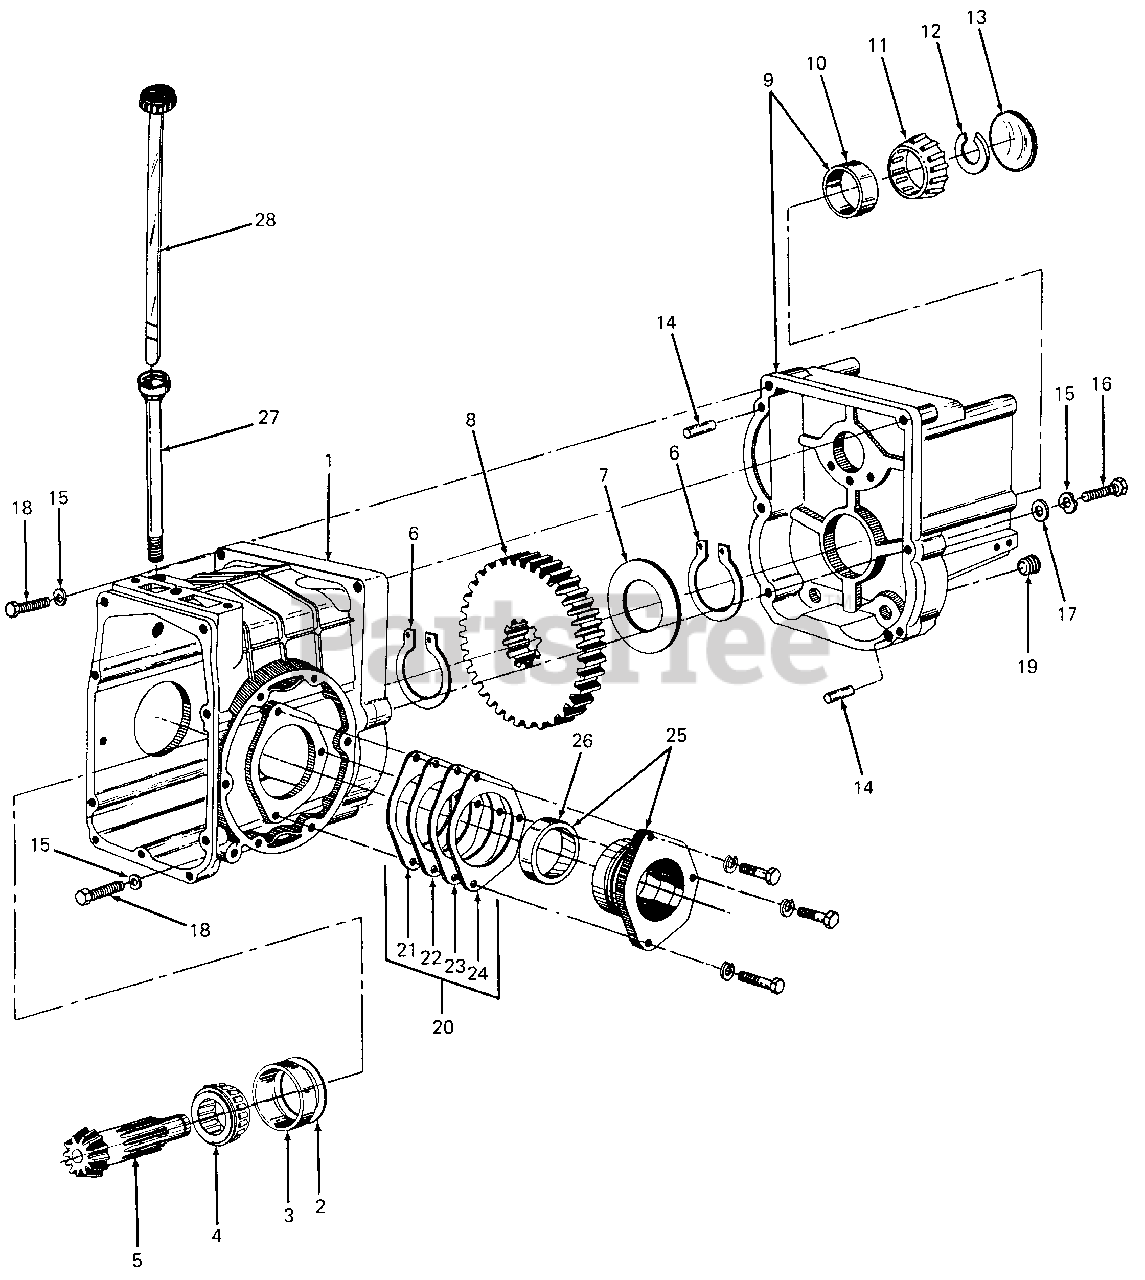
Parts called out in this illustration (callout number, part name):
1	Housing Assy, Rear Transaxle
2	Shim, Rear Bearing Cup, .004 Thk
3	Cup, Roller Bearing
4	Cone, Roller Bearing
5	Shaft, Bevel Pinion
6	Ring, Retaining, 1.312 Dia
7	Spacer, Gear
8	Gear, Reduction - 66T
9	Housing Assy, Adapter w/Cup
10	Cup, Roller Bearing
11	Cone, Roller Bearing
12	Retainer, Front Bearing, .125 Thk
13	Plug, Expansion, 2.12 OD
14	Pin, Dowel, 3/8 Dia X 5/8 Lg
15	Washer, Spring, .445 X .75 X .017 Thk
16	Screw, Hex Cap, 7/16-14 X 2.5 Lg GR5
17	Washer, Flat, .46 X .875 X .060 Thk
18	Screw, Hex Cap, 7/16-14 X 1.75 Lg GR5
19	Plug, Drain
20	Shim Package
21	Shim, Bearing Retainer, .004 Thk
22	Shim, Bearing Retainer, .007 Thk
23	Shim, Bearing Retainer, .014 Thk
24	Shim, Bearing Retainer, .028 Thk
25	Retainer Assy, Bearing w/Cup
26	Cup, Roller Bearing
27	Tube, Dipstick
28	Blade Assy, Dipstick
